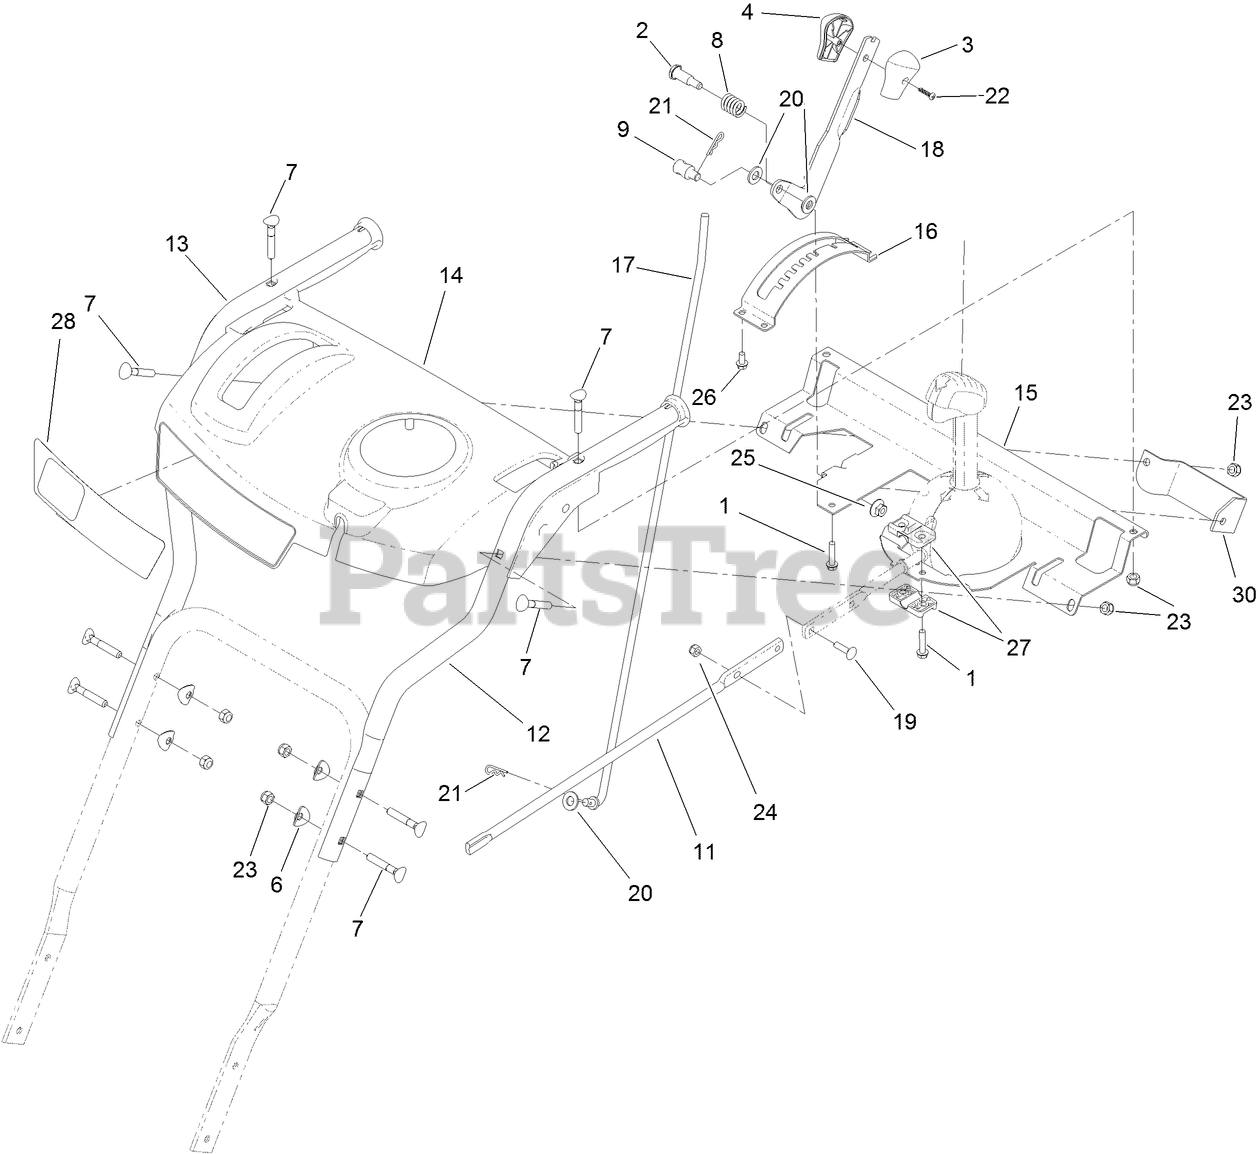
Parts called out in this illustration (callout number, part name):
1	SCREW-PLASTITE, HWH
2	SCREW-SHOULDER, HH
3	KNOB-SHIFT, LH
4	KNOB-SHIFT, RH
6	WASHER-CUP
7	SCREW-HANDLE
8	SPRING-COMPRESSION
9	TRUNNION-ROD
11	ROD-CHUTE, FRONT
12	HANDLE-UPPER, LH
13	HANDLE-UPPER, RH
14	PANEL-CONTROL, MASTER
15	SUPPORT-PANEL, CONTROL
16	MOUNT-SELECTOR, SPEED
17	ROD-SELECTOR, GEAR
18	SELECTOR-SPEED
19	BOLT-CARR
20	WASHER-FLAT
21	PIN-HAIR
22	SCREW-PPH
23	NUT-HEX
24	NUT-HEX
25	NUT-HF
26	SCREW-PLASTITE
27	SUPPORT-ROD
28	DECAL-PANEL, CONTROL
30	PLATE-SUPPORT, SHIFT
